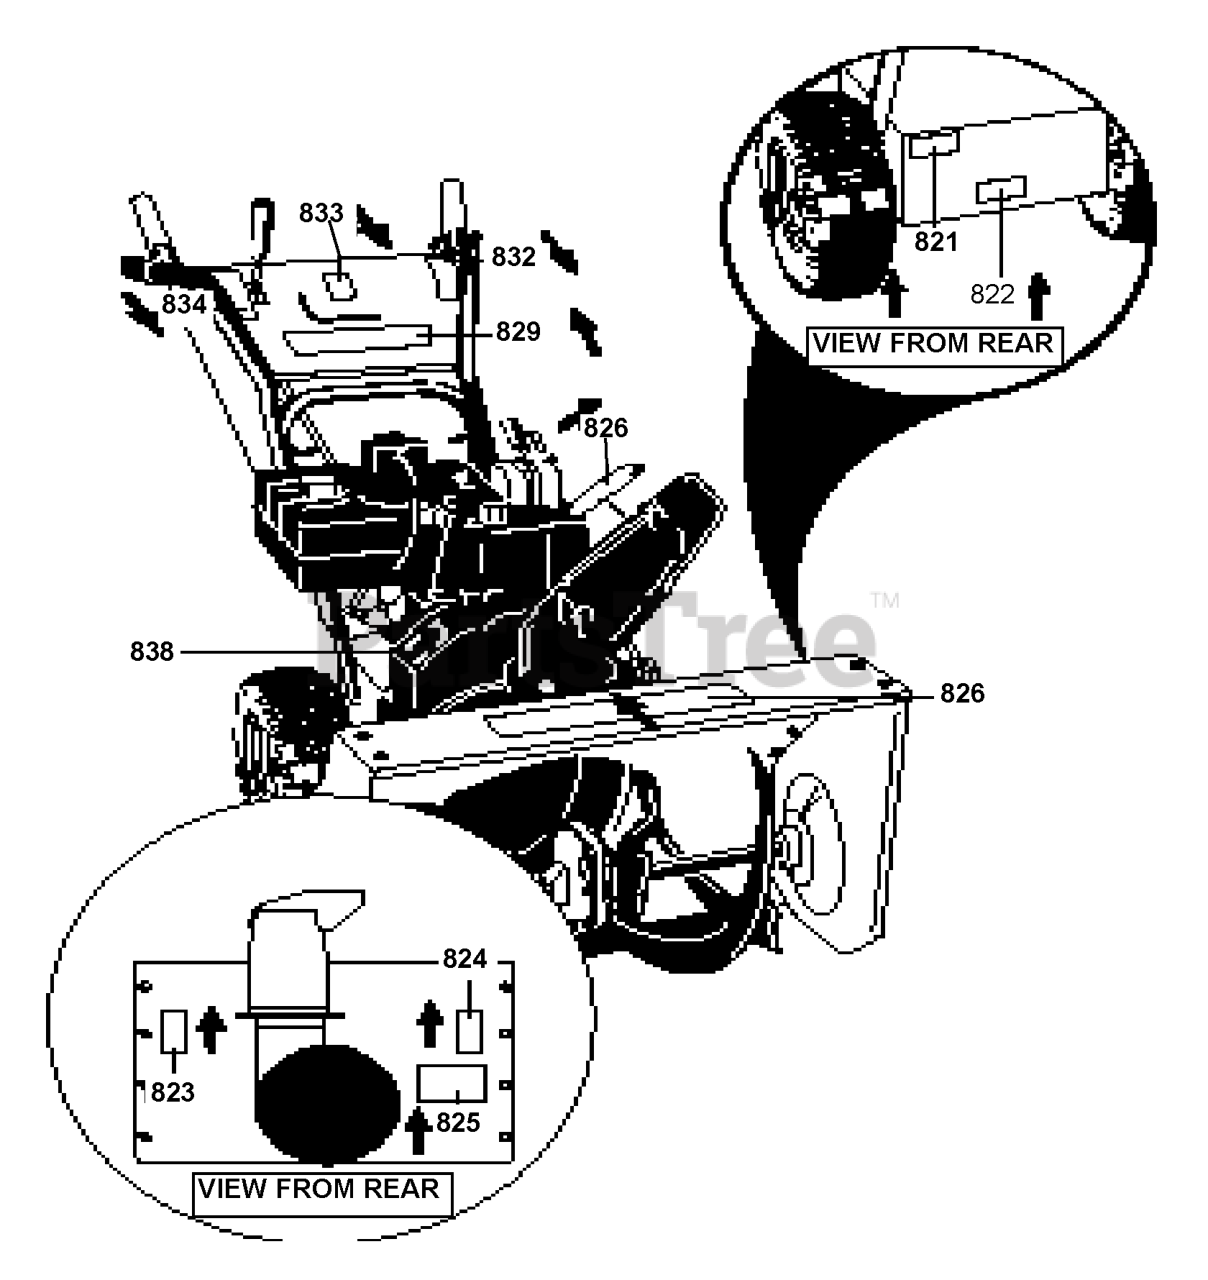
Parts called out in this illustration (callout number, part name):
821	NOT A SEVICABLE PART
822	DECAL-OVER ADJ OF DISC
823	DECAL, DANGER CHUTE
824	DECAL-DANGER AUGER/FOOT
825	DECAL, DANGER
826	DECAL-ST824E
829	DECAL, CROWN
832	DECAL, TRACTION DRIVE
833	DECAL-SNOW CONDITIONS
834	DECAL, GEAR SELECTOR
835	DECAL, CONTROL PANEL
838	DECAL, BELT STRETCH & ADJ
